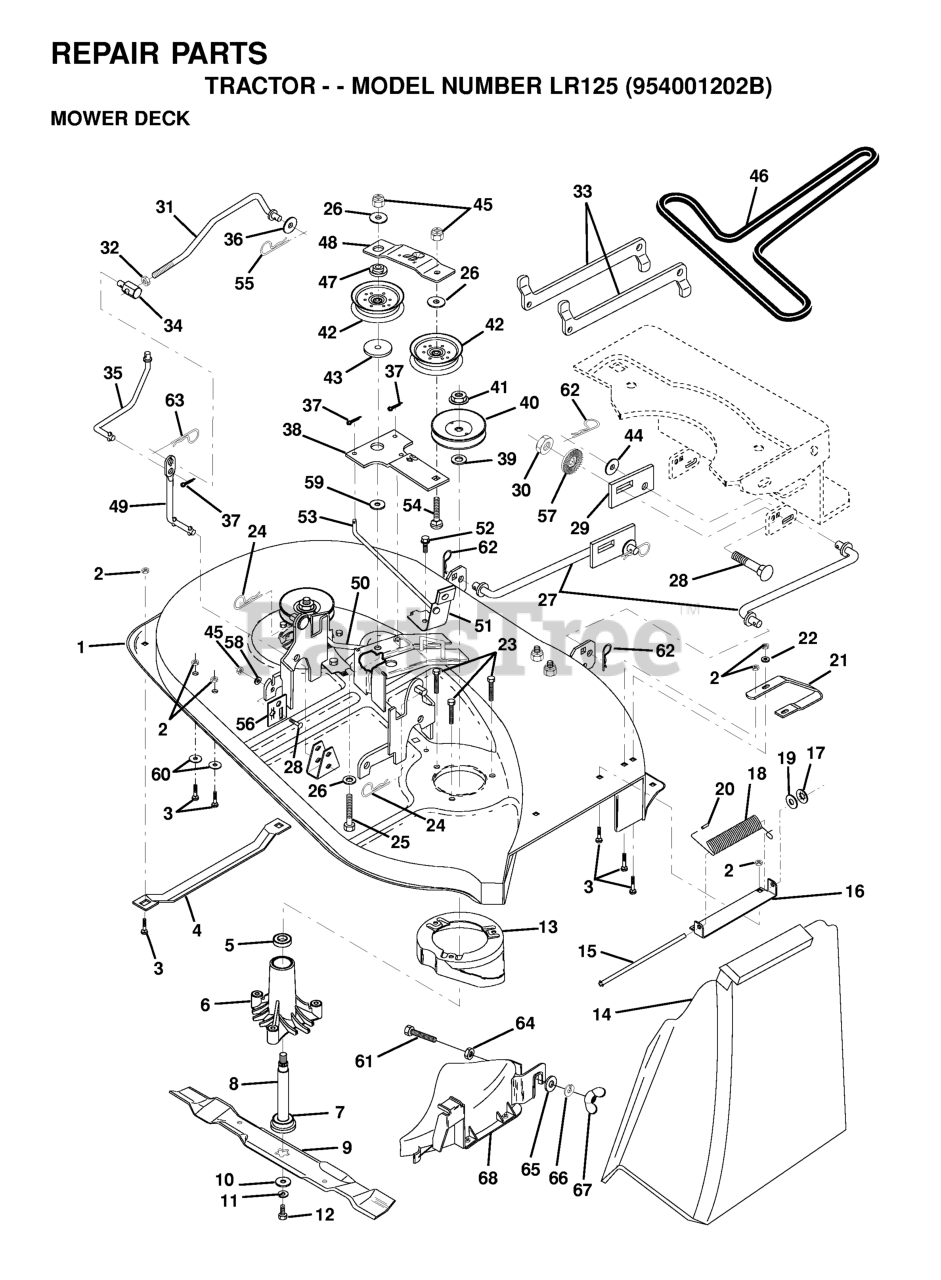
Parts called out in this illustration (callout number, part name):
1	DECK ASSY
2	LOCKNUT
3	RP BOLT 5/16-18 X3/4 ZN/YEL GR
4	RUNNER-LH M
6	HOUSING.MANDREL.VENTED (MACHD)
7	BEARING.BALL.#6204.(MANDREL)
8	SHAFT ASM VENT
9	BLADE 38" V MULCH
10	WASHER.BLADE
11	LOCKWASHER
12	BLADE BOLT
13	STRIPPER
14	SHIELD.DEFLECTOR.MOWER.38.BL
15	ROD-HINGE T
16	BRACKET, DEFLECTOR
17	NUT PUSH M
18	SPRING TORSION
19	Washer 11/32 x 5/8 x 16 Ga SD
20	CAP-SLEEVE LT
21	RUNNER.RH.38
22	WASHER M
23	SCREW
24	RETAINER-SPRNG RB
25	BOLT
26	WASHER GT
28	BOLT D
29	PLATE SLIDE LINK
30	NUT
31	ROD.CLUTCH.PRIMARY
32	NUT
33	ARM REAR SUSPENSION
35	CLUTCH ROD
36	WASHER
37	COTTER PIN
39	WASHER
40	MANDREL PULLEY
41	NUT
42	PULLEY.IDLER.FLAT.MOWER.BLK.PT
43	SPACER RETAINER
46	BELT
47	SPACER.IDLER.ARM
48	STIFFENER.IDLER.ARM
50	BRAKE ROD LH
51	BRAKE ASSEMBLY
52	SCREW.THDROL.5/16-18X3/4.TTY
53	BRAKE ROD RH
55	SPRING TI
56	ADJUSTMENT PLATE
57	WASHER SERRATED DISC 13/32 X 1
58	WASHER T
59	HARDENED WASHER
61	Bolt, Hex Head 3/8-16 x 1-1/4
62	SPRING RETAINER
63	RETAINER M
64	LOCKNUT
65	WASHER
66	WASHER, LOCK 3/8
68	COVER.MULCHING.38" (2 2)
